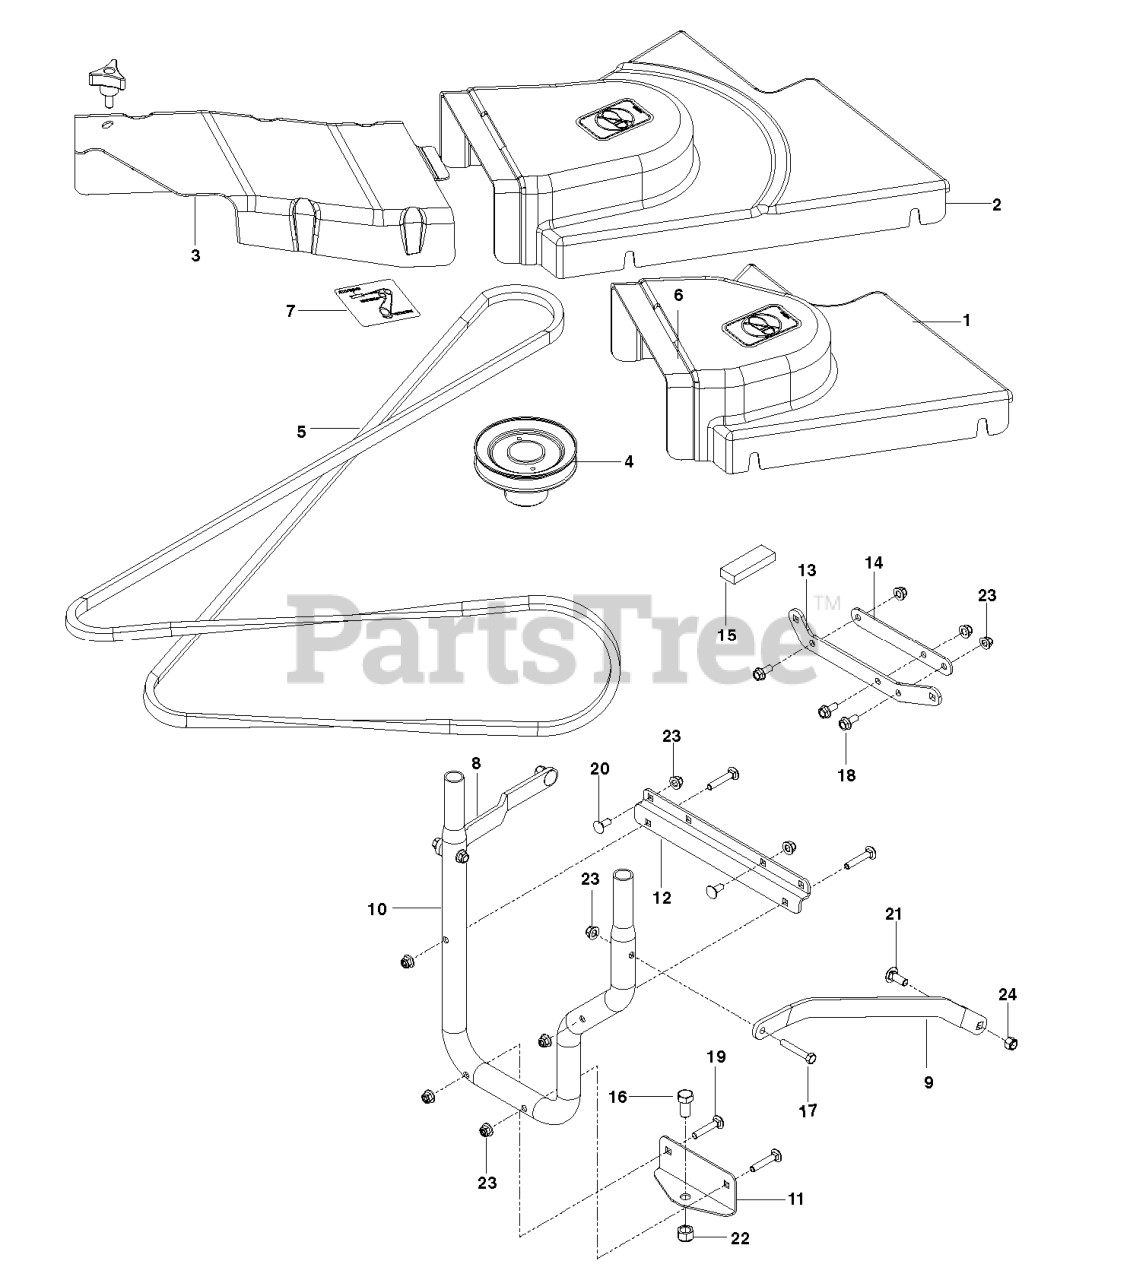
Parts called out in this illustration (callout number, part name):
1	SHIELD, BELT, 52"
2	SHIELD, BELT, 61"
3	COVER, BELT
4	PULLEY, 52"
5	BELT, 48/52"
6	DECAL, NO STEP
7	DECAL, BELT ROUTING
8	STRAP.LH.BLACK
9	STRAP.RT.BLACK
10	MOUNT.TUBE.COLLECTIONS
11	MOUNT, HITCH, LOWER
12	MOUNT HITCH UPPER
13	BRKT, SUPPORT, BLK
14	SPACER, PLATE, BLK
15	FOAM STRIP, FUEL TANK
17	HCS 5/16-18 X 2 GR 5 ZD
18	HHFS 5/16-18 X 3/4
19	RHSNB 5/16-18X1 3/4
20	RP BOLT 5/16-18 X3/4 ZN/YEL GR
21	BOLT D
22	NUT.LK.W/WSH.1/2.
23	5/16-18 NYLOC FLANGE NUT
24	NUT 3/8-16 NYLOC
